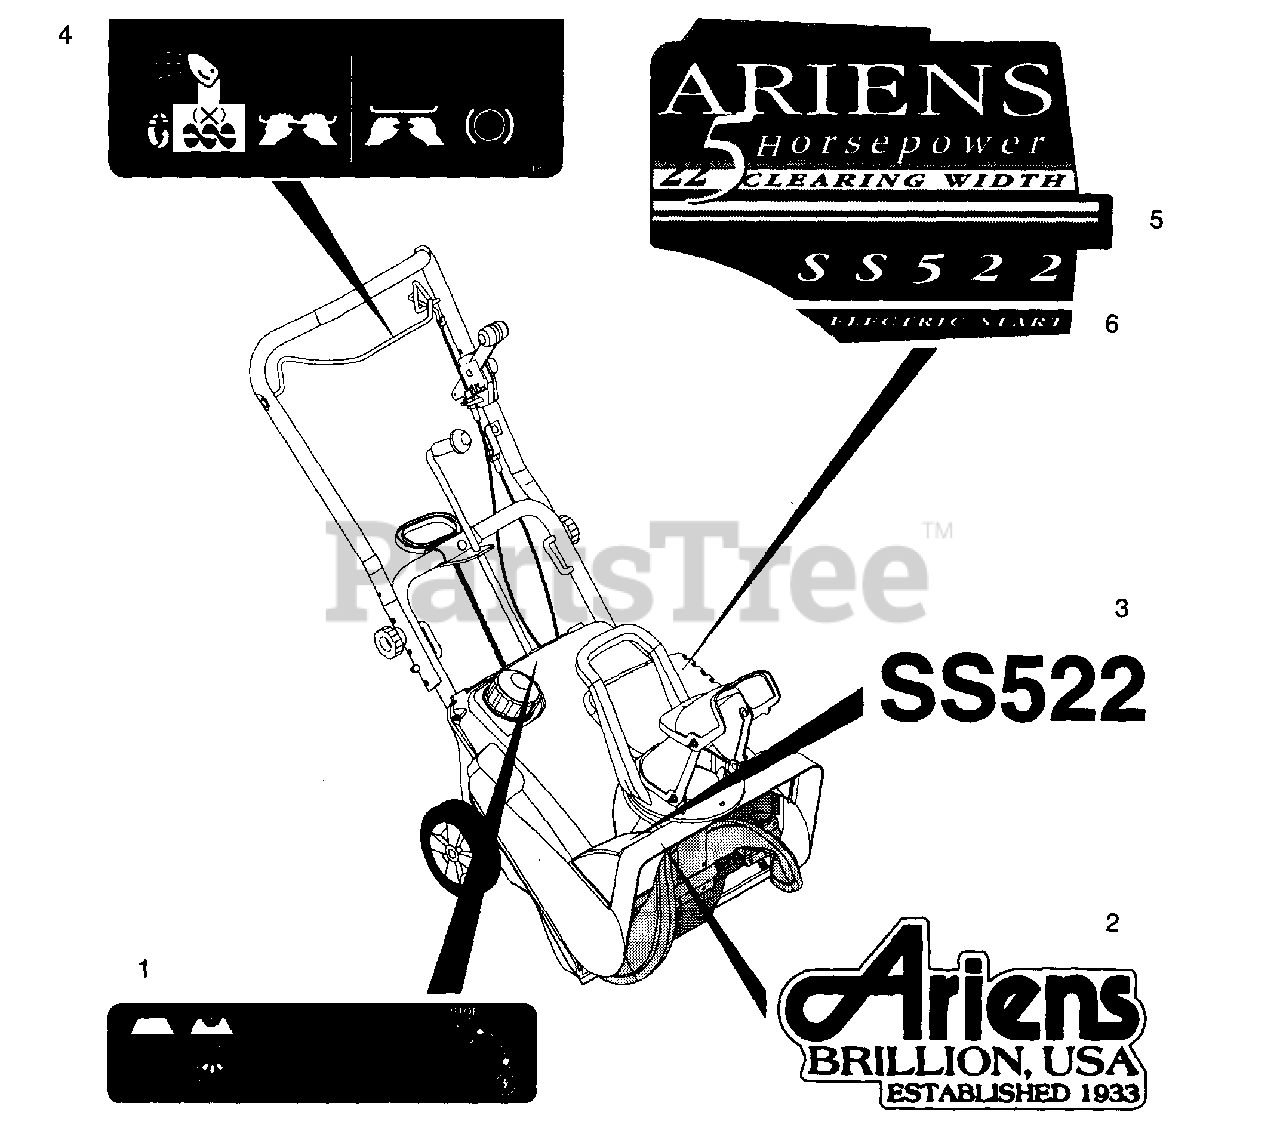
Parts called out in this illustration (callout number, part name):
1	DECAL-PANEL
2	DECAL-LESCO
3	DECAL SS522
4	DECAL-AUGER/IMPELLER BAIL
5	SET-DECAL 5 HP ELEC
